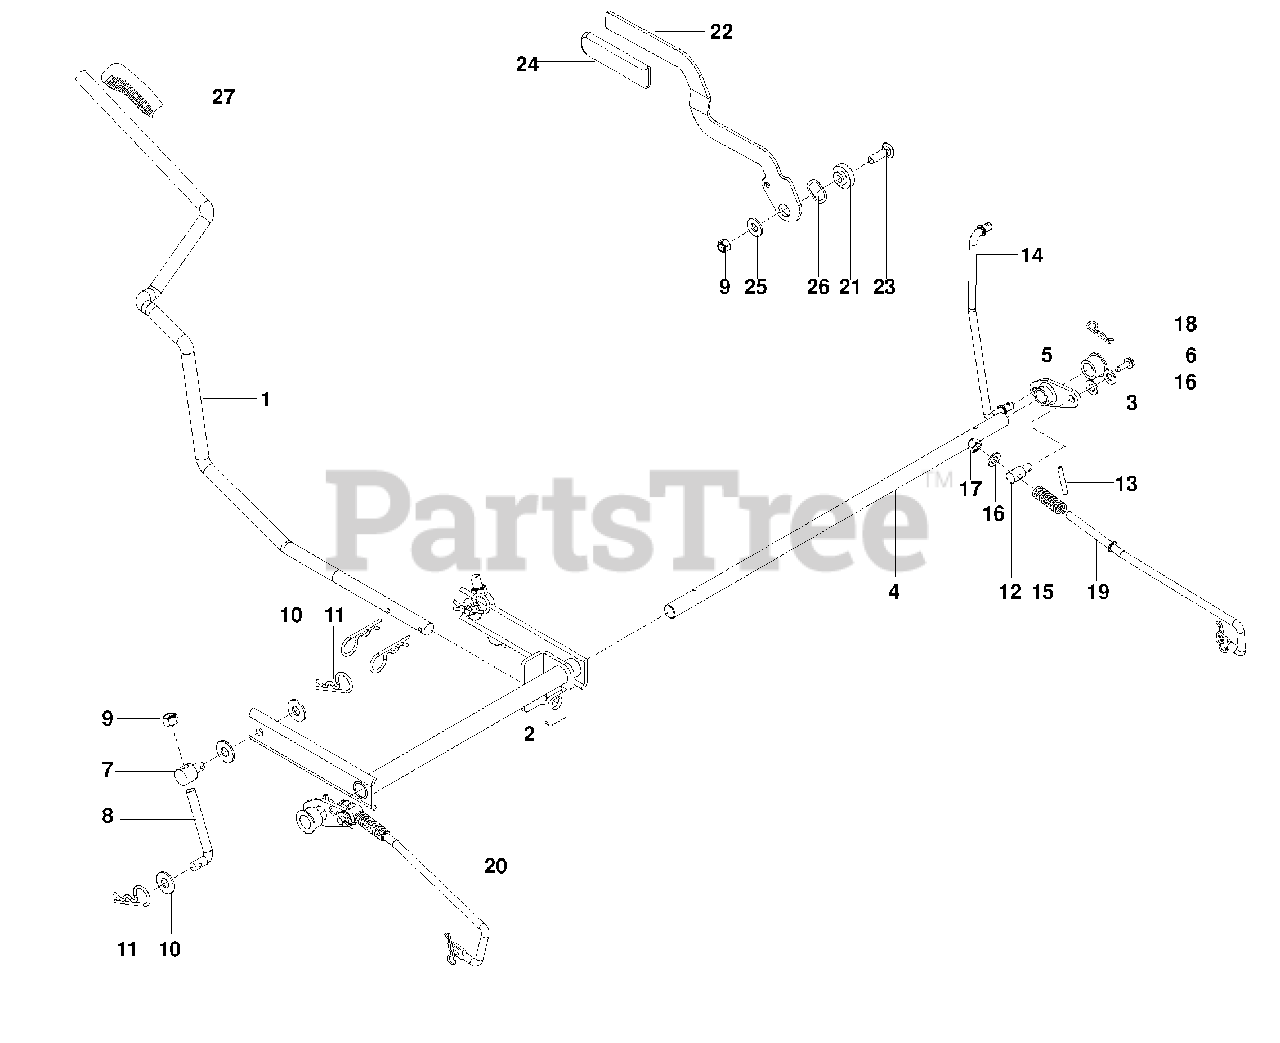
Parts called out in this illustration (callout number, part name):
1	HANDLE, LIFT
2	SHAFT, LIFT
3	BELLCRANK, BRAKE
4	ROD, BRAKE
5	BUSHING, PLASTIC
6	SCREW 10-24 x 5/8" WSH HD
8	L-ROD 31/8"
9	NUT 3/8-16 HEX NYLOC
10	WASHER 3/8 FLAT STD
12	SWIVEL, BRAKE
13	ROLL PIN 3/16"
14	LINKAGE, UPPER
16	WASHER 5/16 SAE FLAT
17	NUT 5/16-18 HEX NYLOC
18	HAIRPIN COTTER
19	LINKAGE, BRAKE RT
20	LINKAGE, BRAKE LT
21	PIVOT, BRAKE ARM
22	HANDLE, BRAKE
23	RHSNB 3/8-16 x 1 1/4
24	GRIP, BRAKE HANDLE
25	WASHER 7/16 SPRING DISK
26	WASHER, .825
27	GRIP, LIFT HANDLE
